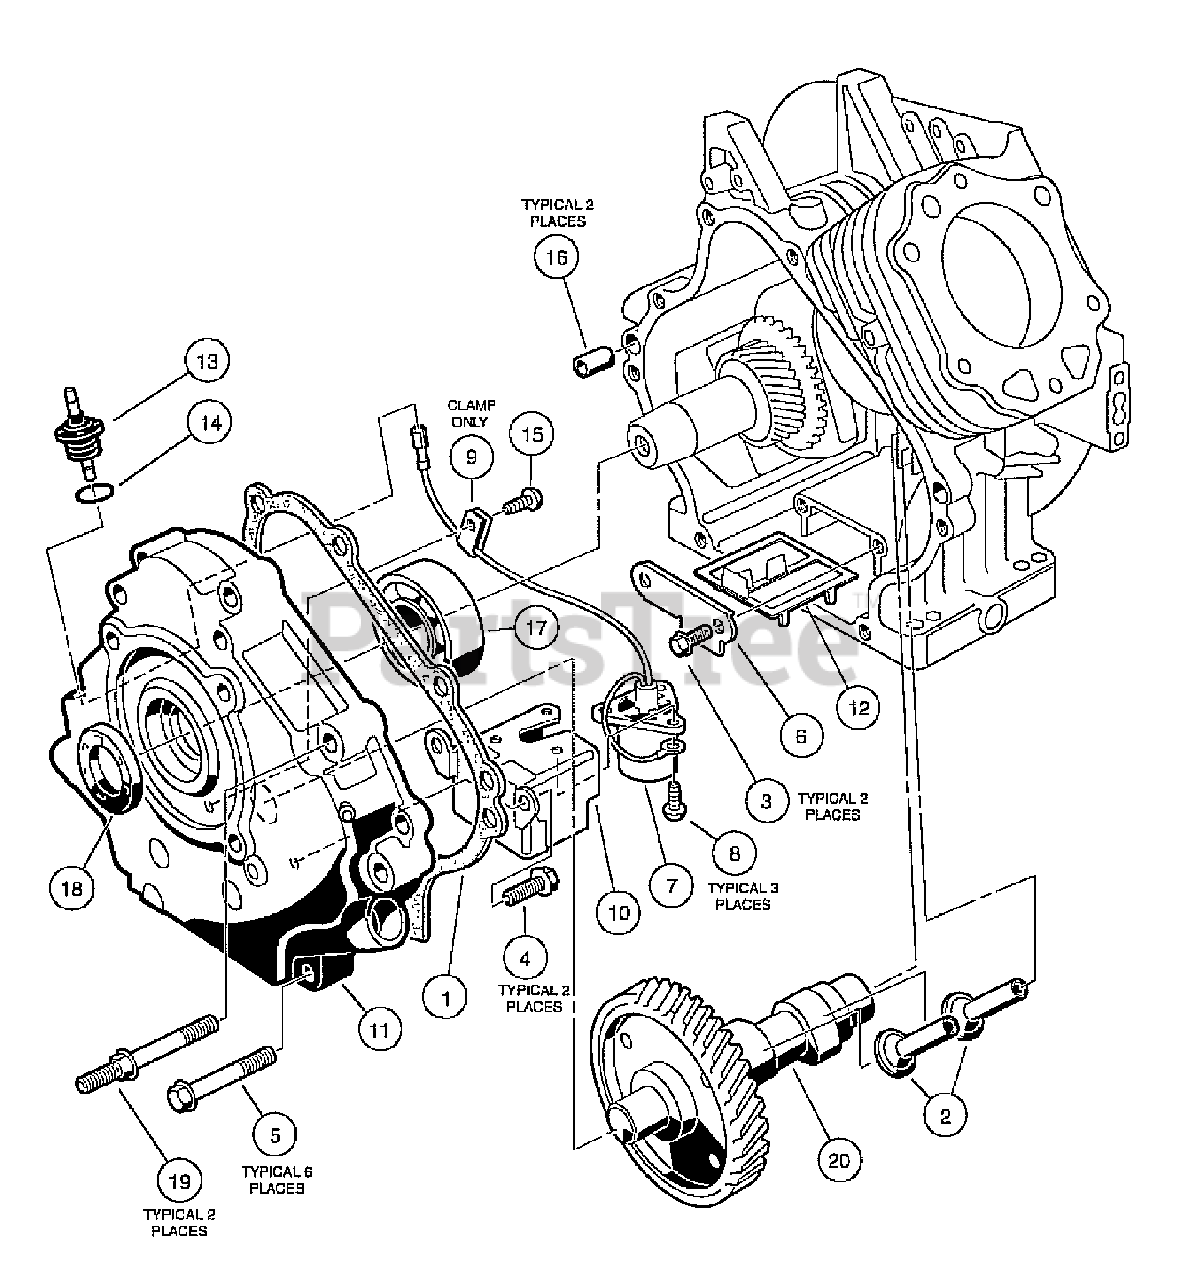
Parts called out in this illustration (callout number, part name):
1	Gasket, Crankcase Cover
2	Tappet
3	Bolt, Flange Head, M5 x 0.8 x 8 mm
4	Bolt, Flange Head, M6 x 1 x 12 mm
5	Bolt, Flange Head, MB x 1.25 x 45 mm
6	Plate, Oil Filter Screen
7	Sensor, Oil Level
8	Screw, Cross Pan-Head, M4 x 0.7 x 8 mm
10	Bracket, Switch, Oil Level
11	Cover, Crankcase
12	Screen, Oil Filter
13	Connector, Cord
17	Bearing, Ball
18	Seal, Crank Shaft
19	Bolt, Two-Ended, M8 x 1.25 x 69 mm
20	Camshaft Complete, FE290
